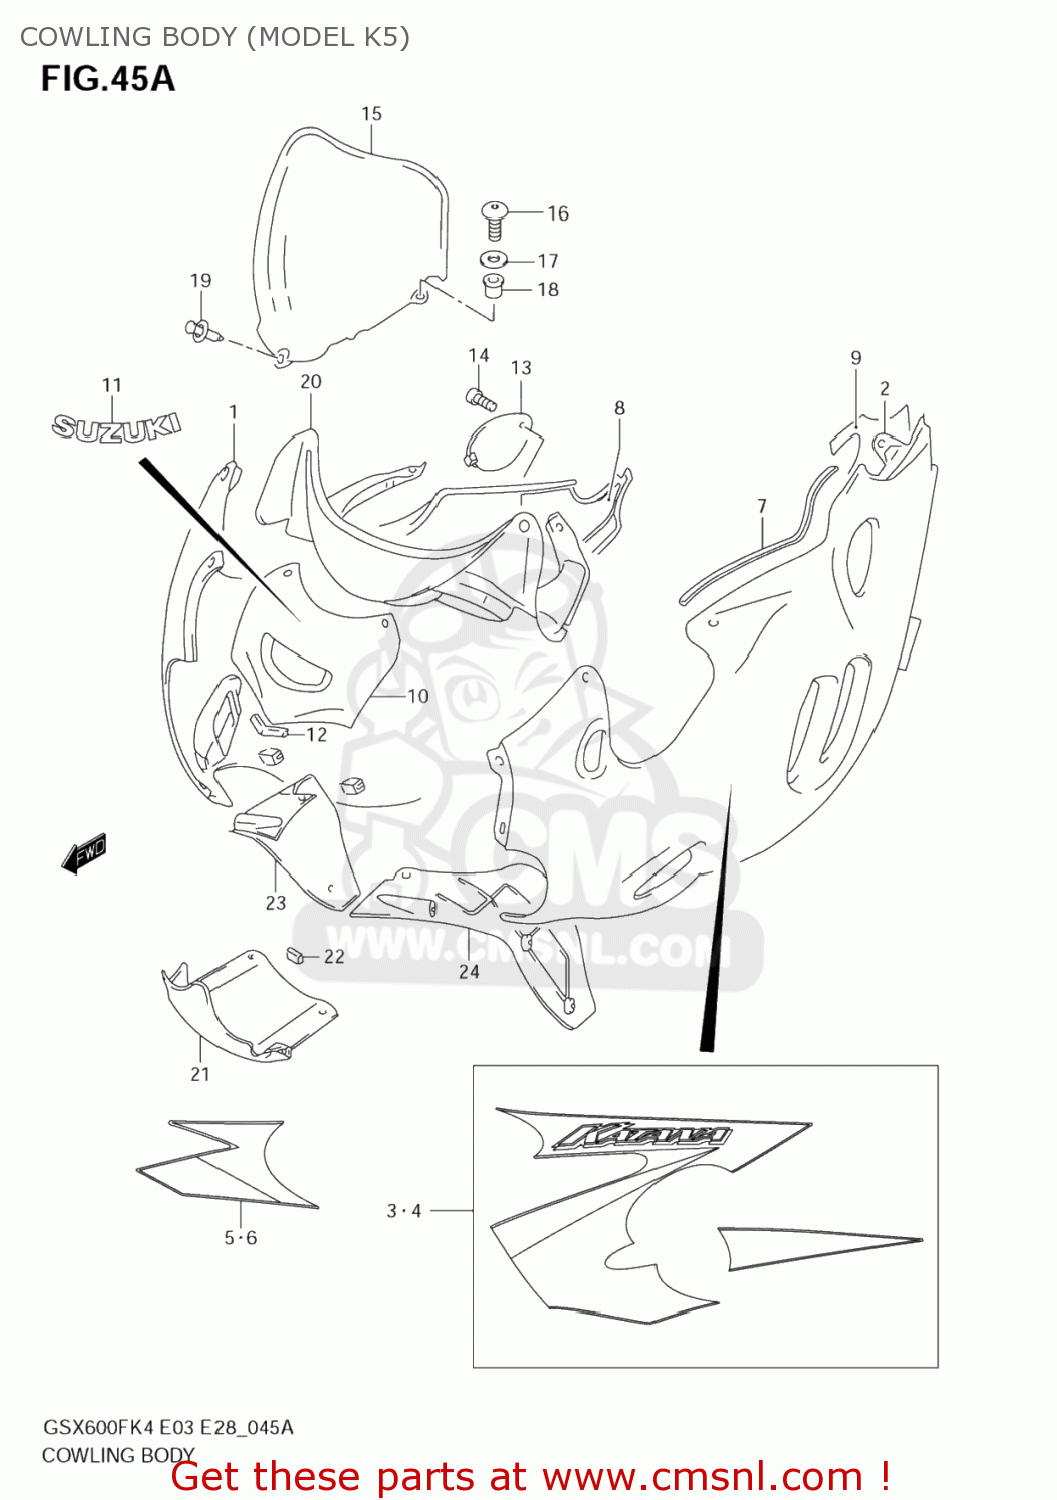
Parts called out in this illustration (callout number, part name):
1	COWLING ASSY,SIDE,R
2	COWLING ASSY,SIDE,L
3	TAPE SET,COWL SIDE,R
4	TAPE SET,COWL SIDE,L
5	TAPE,COWL SIDE,R
6	TAPE,COWL SIDE,L
7	MOLD,COWLING
8	SHIELD,COWLING COVER,R
9	SHIELD,COWLING COVER,L
10	PANEL,COWLING CTR UPR
11	EMBLEM,FR
12	CUSHION,CTR PANEL UPR
13	LID,OIL
14	SCREW(6X16)
15	WINDSCREEN
16	SCREW(5X14)
17	WASHER
18	NUT
19	CLIP(BLACK)
20	PANEL,METER
21	PANEL,COWLING CTR LWR
22	CUSHION,CENTER PANEL,LOWER
23	PANEL,COWLING INNER,R
24	PANEL,COWLING INNER,L
